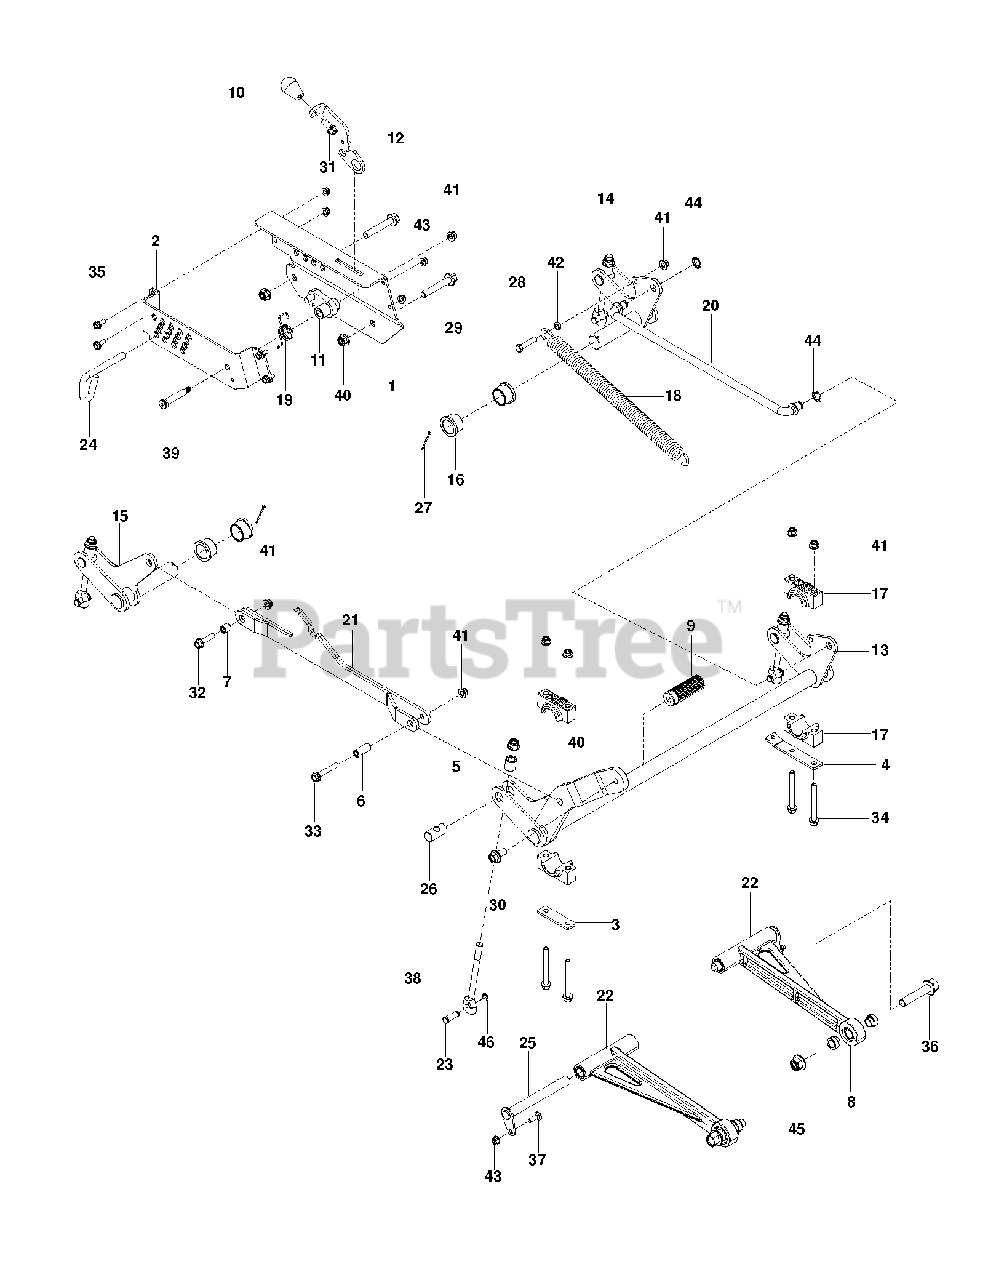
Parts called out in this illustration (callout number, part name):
1	PLATE, HEIGHT INNER ORG
2	PLATE, HEIGHT OUTER ORG
3	PLATE, PILLOW BLACK
4	PLATE, SPRING ANCHOR
5	SPACER, EYEBOLT
6	SPACER, FRONT LIFT STRAP
7	SPACER, REAR LIFT STRAP
8	SPACER, STRUT
9	PEDAL, DECK HEIGHT
10	KNOB - SHIFT
11	LATCH, TRANSPORT WLDMT
12	LEVER, TRANSPORT RELEASE
13	SHAFT DECK LIFT FT
14	SHAFT, LIFT LEFT REAR
15	SHAFT, LIFT RIGHT REAR
16	BUSHING, FLANGE 1.25 X 1.0
17	BLOCK, PILLOW
18	SPRING, EXTENSION
19	SPRING, TORSION
21	WELDMT, DECK STRAP
22	ASSEMBLY, STRUT
23	PIN, 7/16 CLEVIS
24	PIN, HEIGHT
25	PIN, STRUT
26	PIN, TRUNION, EYEBOLT
27	COTTER PIN 1/8 X 2
28	HCS 3/8-16 X 1 3/4 GR5
29	HFFS 1/2-13 X 3 GD 5 ZD
30	HHFS 1/2-13 X 1 GR5 ZD
31	HHFS 3/8-16 X 1 GRD 5 ZD
32	HHFS 3/8-16 X 1.50 GR5 ZD
33	HHFS 3/8-16 X 2-1/4 GR 5 ZD
34	HHFS 3/8-16 X 3.5 GD 5 ZD
35	HHFS 5/16-18 X 3/4
36	HHFS 5/8-11 X 3.0 GD 8 ZD
37	RHSNB 5/16C X 1
38	EYEBOLT, DECK LIFT
39	BOLT, SHOULDER, 1/2 X 2.25
40	NUT, 1/2-13 HEX FLG NYLOC ZD
41	NUT 3/8-16 HEX FLG NYLOC ZD
42	NUT 3/8-16 HEX JAM
43	5/16-18 NYLOC FLANGE NUT
44	NUT 5/8 PUSH
45	NUT 5/8-11 FLG NYLOC ZD
46	RING, E, 7/16
